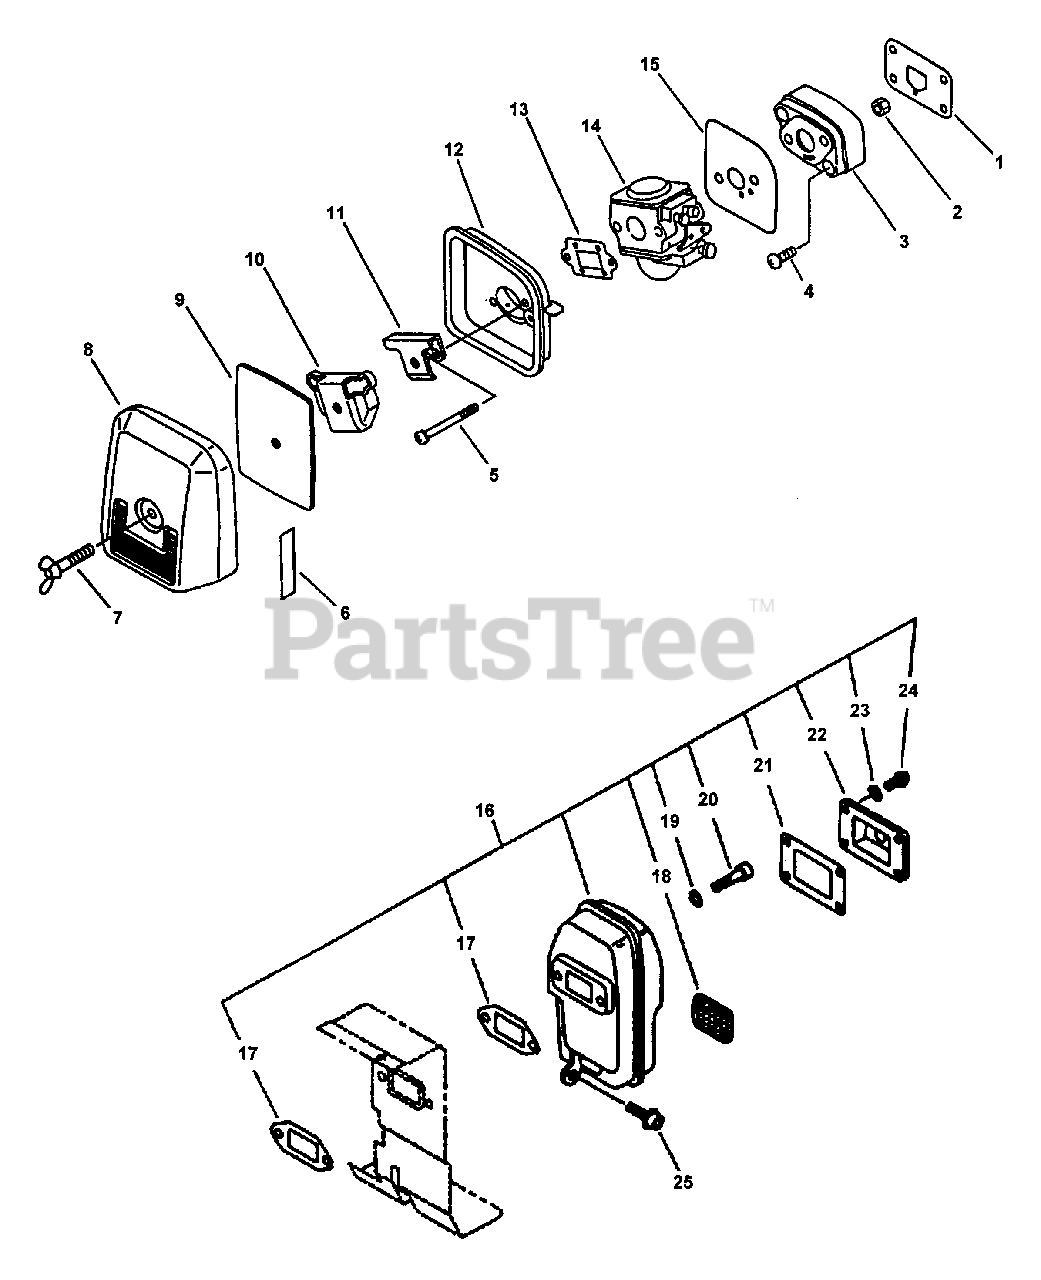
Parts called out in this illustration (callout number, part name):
1	GASKET, INTAKE
3	INSULATOR, INTAKE
4	SCREW - 5X22
5	SCREW - 5X55
6	LABEL - CHOKE
7	THUMBSCREW
8	COVER, AIR FILTER
9	FILTER, AIR - HEAVY DUTY
10	PLATE, PREVENT
11	PLATE, PREVENT
12	AIR FILTER CASE ASSY
14	CARBURETOR WT-417
15	GASKET, INTAKE
16	MUFFLER ASSY
17	GASKET, EXHAUST
18	SCREEN, SPARK ARRESTOR
19	WASHER - 5
20	SCREW - 5X60
21	GASKET, EXHAUST
22	GUIDE, EXHAUST
23	LOCKWASHER - 4
24	SCREW - 4X12
25	SCREW - 5X16
